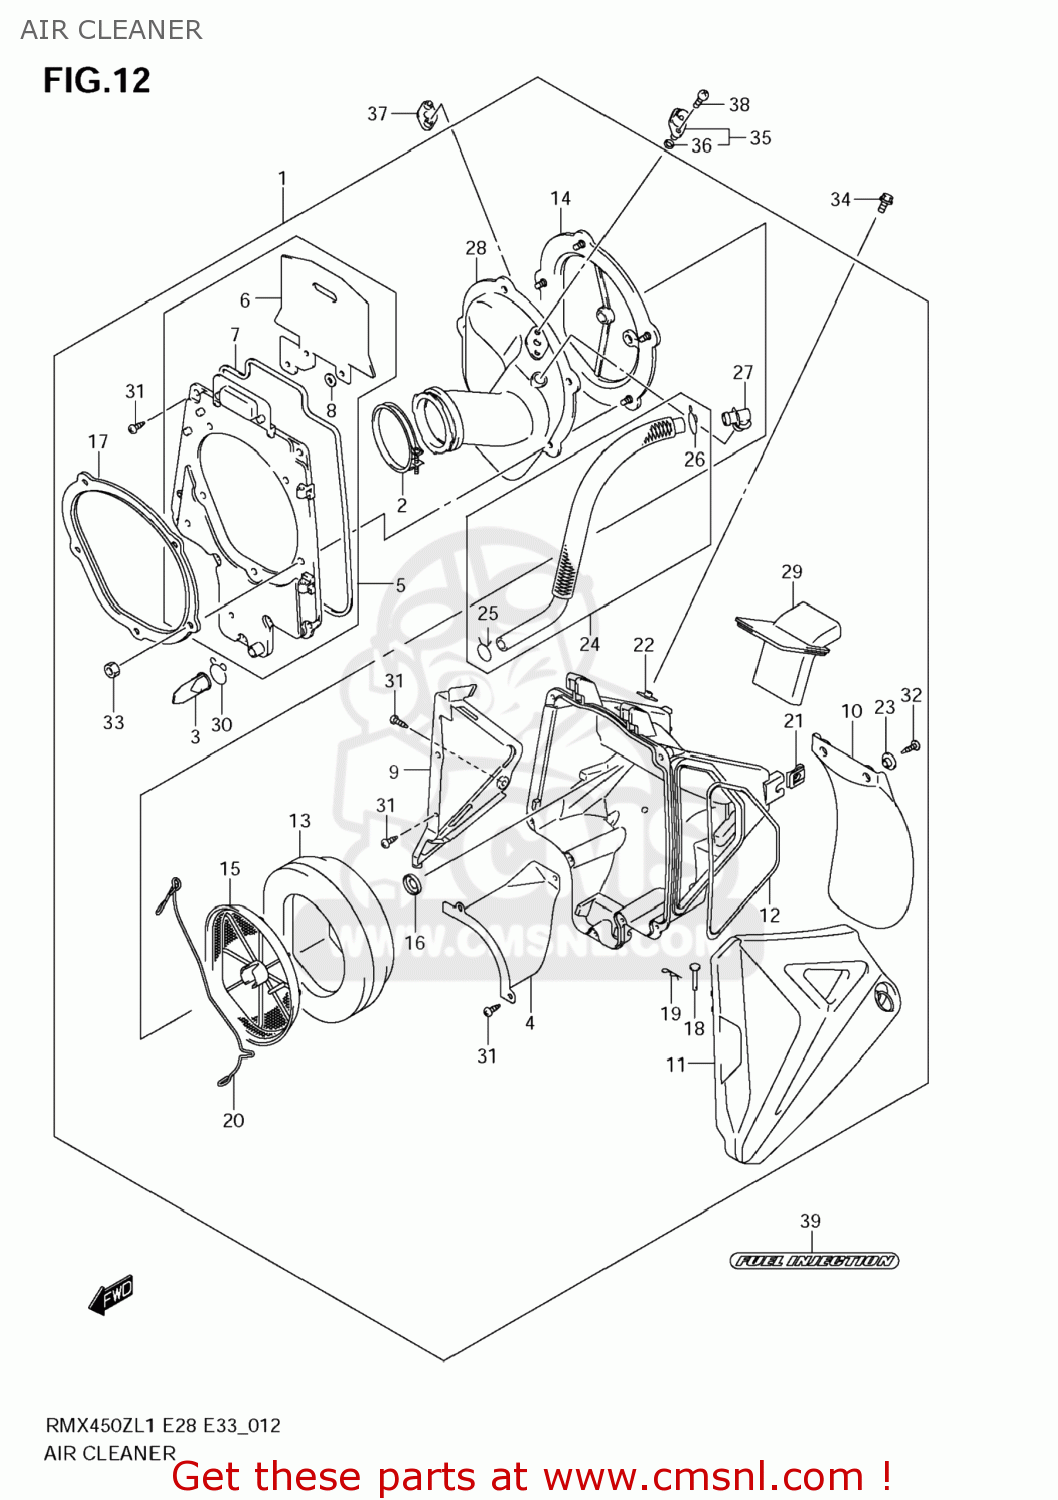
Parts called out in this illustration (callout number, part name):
1	CLEANER ASSY,AIR(WHITE)
2	CLAMP
3	CAP,DRAIN
4	PLATE,HEAT GUARD
5	CASE,AIR CLEANER FR
6	COVER,AIR CLEANER
7	GASKET,CASE (NAS)
8	NUT,PUSH
9	COVER,SIDE,R
10	MUDGUARD
11	CAP,AIR CLEANE
12	GASKET,CASE (NAS)
13	FILTER ASSY
14	BASE,FILTER
15	HOLDER,FILTER
16	SPACER
17	PLATE,FILTER BASE
18	PIN,HINGE
19	PIN,SNAP
20	SPRING
21	RECEPTACLE
22	NUT,AIR CLEANER
23	COLLAR
24	TUBE,BREATHER
25	CLIP
26	CLIP
27	JOINT
28	TUBE,OUTLET
29	TUBE,INLET
30	CLIP
31	SCREW
32	SCREW
33	NUT
34	BOLT
35	SENSOR,AIR TEM
36	O RING
37	BRACKET,AIR TEMP SENSOR
38	SCREW
39	EMBLEM,FRAME COVER
